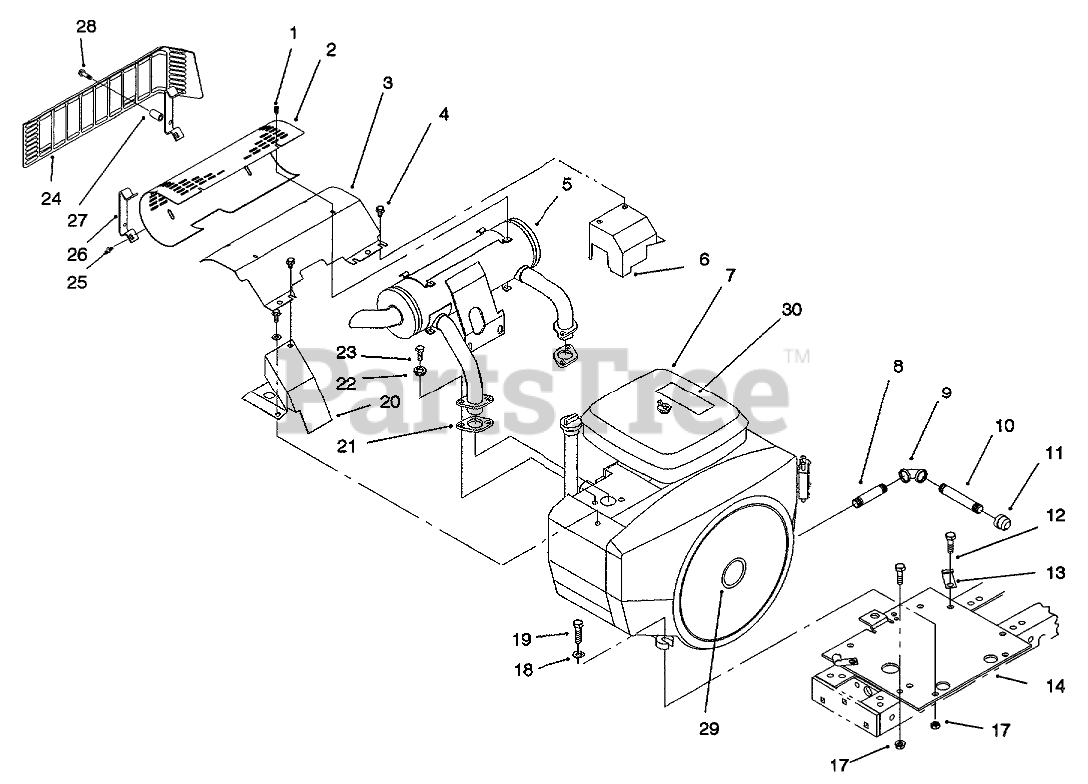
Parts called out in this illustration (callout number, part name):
1	SCW 10-24 STAINLESS
2	SHIELD - HEAT
3	Baffle-Deflector
4	SCREW-HWHTF
5	MUFFLER-EXHAUST
6	COVR-EXHAST (BLACK)
7	Engine-Onan
8	Pipe
9	ELBOW 3/8 90 DEG
10	PIPE-NIPPLE 3/8 X 4"
11	CAP-PIPE
12	SCREW-HH
13	CLIP
14	Plate-Engine
17	NUT-LOCK, NI
18	WASHER-FLAT
19	SCREW-HH
20	COVR-EXHAST (BLACK)
21	GASKET
22	WASHER-LOCK
23	SCREW-HH
24	SHIELD - HEAT (BLACK)
25	Screw-Phcr
26	Bar-Guard
27	SPACER
28	SCREW-HWH
29	NAME-PLATE TORO LOGO
30	DECAL-PWR PLUS 20 PL
